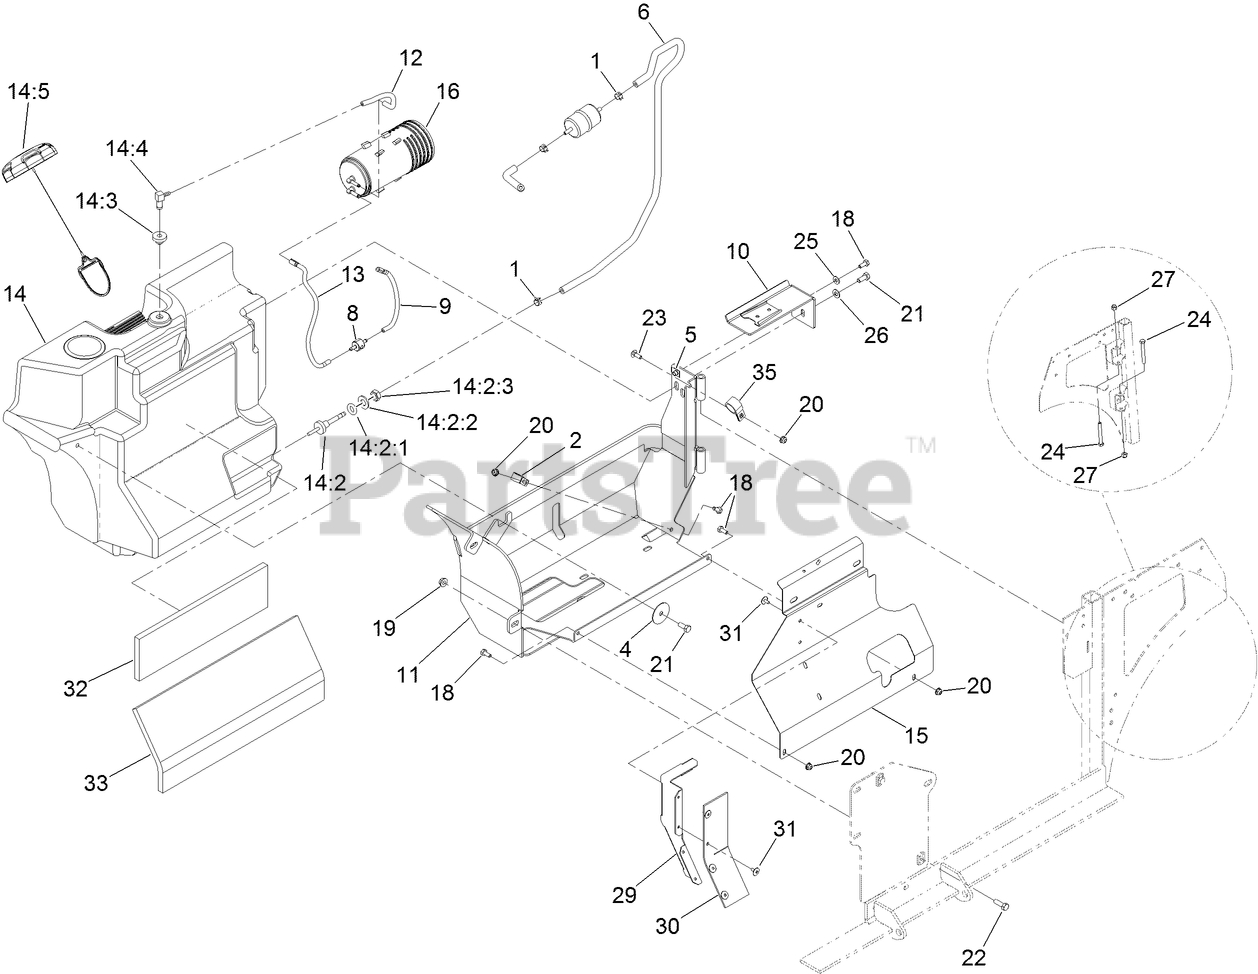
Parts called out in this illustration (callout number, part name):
1	CLAMP-HOSE
2	CLIP-LOOM
4	WASHER
6	FUEL LINE ASM
8	VALVE-CHECK, VACUUM
9	HOSE-VENT, FORMED
10	CANISTER BRACKET ASM
11	TANK FRAME ASM
12	HOSE-VENT, FORMED
13	HOSE-VENT, FORMED
14	FUEL TANK ASM
14:2	FITTING-FUEL, BULKHEAD
14:2:1	O-RING,BULKHEAD FITTING
14:2:2	WASHER-FLAT
14:2:3	NUT-JAM
14:3	BUSHING
15	PANEL-TANK SHIELD
16	CANISTER-CARBON, 800CC
18	SCREW-HH
19	NUT-HF
20	NUT-HF
21	SCREW-HH
22	SCREW-HH
23	BOLT-CARR
24	SCREW-HH
25	WASHER-FLAT
26	WASHER-PLAIN
27	NUT-LOCK, NI
29	DEFLECTOR-AIR
30	FLAP-RUBBER
31	RIVET-POP
32	INSULATION-FOAM PAD, FRONT
33	INSULATION-FOAM PAD, REAR
35	R-CLAMP
